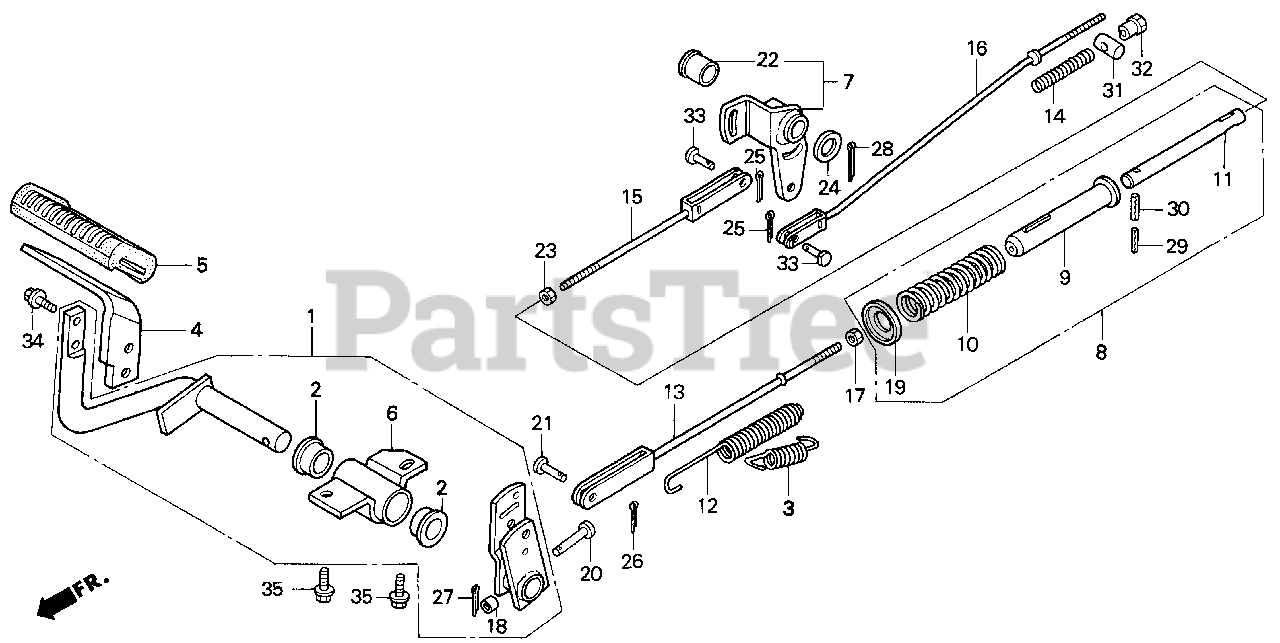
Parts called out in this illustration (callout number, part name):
1	ARM ASSY., BRAKE PEDAL
2	BUSH, BRAKE PEDAL
3	SPRING, BRAKE PEDAL
4	BRACKET, BRAKE PEDAL
5	RUBBER, BRAKE PEDAL
6	PIVOT, BRAKE PEDAL
7	ARM ASSY., BRAKE ROD
8	PIPE ASSY., FOOT BRAKE (H.S.T.)
9	PIPE, BRAKE
10	SPRING, FOOT BRAKE LOAD SETTING
11	SHAFT, SPRING SETTING
12	SPRING, BRAKE DAMPER
13	ROD A, RR. BRAKE
14	SPRING A, BRAKE ROD
15	ROD B, RR. BRAKE
16	ROD, RR. BRAKE (C)
17	NUT, GOVERNOR ARM FIXING
18	COLLAR (10X5)
19	WASHER, BRAKE SPRING SETTING
20	PIN, BRAKE SHAFT
21	PIN (5.3X17)
22	BUSH (16X18X25)
23	NUT, HEX. (6MM)
24	WASHER, PLAIN (16MM)
25	PIN, COTTER (1.6X12)
26	PIN, COTTER (2.0X12)
27	PIN, COTTER (2.0X15)
28	PIN, COTTER (3.0X45)
29	PIN, SPRING (3X28)
30	PIN, SPRING (5X28)
31	JOINT A, BRAKE ARM
32	NUT A, BRAKE ROD ADJUSTING
33	PIN B, BRAKE ROD JOINT
34	BOLT, FLANGE (8X18)
35	BOLT, FLANGE (10X18)
